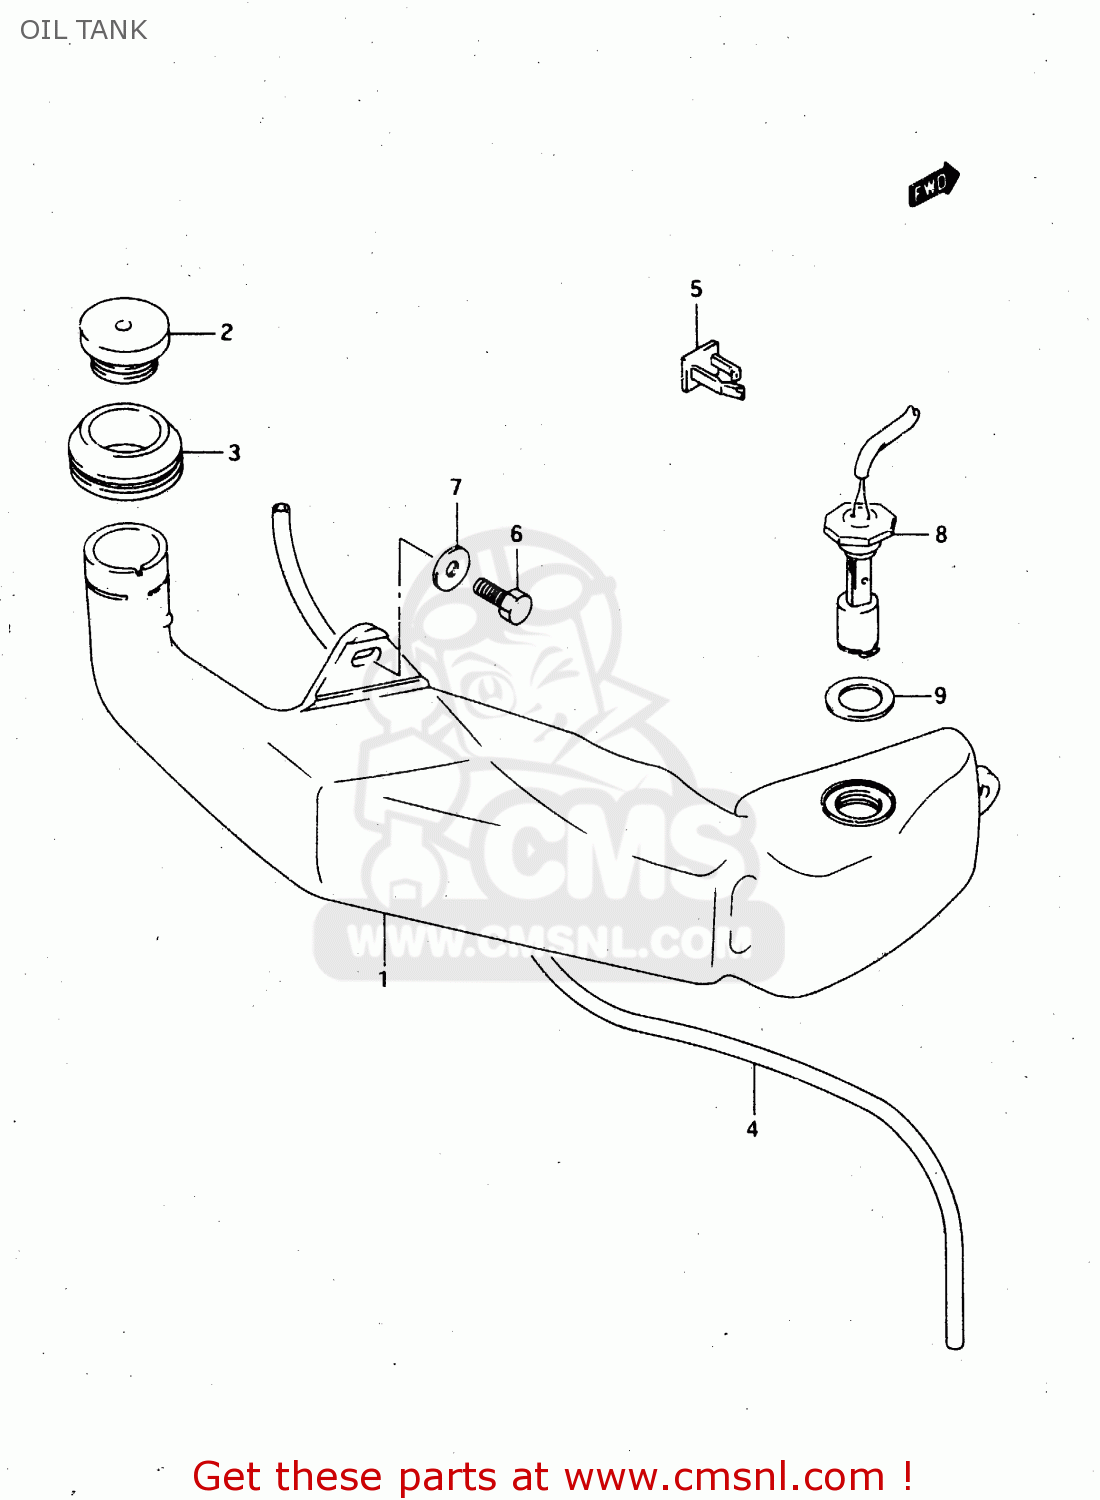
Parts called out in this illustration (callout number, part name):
1	TANK,OIL
2	CAP,OIL TANK
3	RUBBER,OIL TANK INLET
4	HOSE(5X8.2X600)
5	CLAMP
6	BOLT(6X20)
7	WASHER(6.5X18X1)
8	SWITCH ASSY,OIL LEVEL
9	GASKET (NAS)
